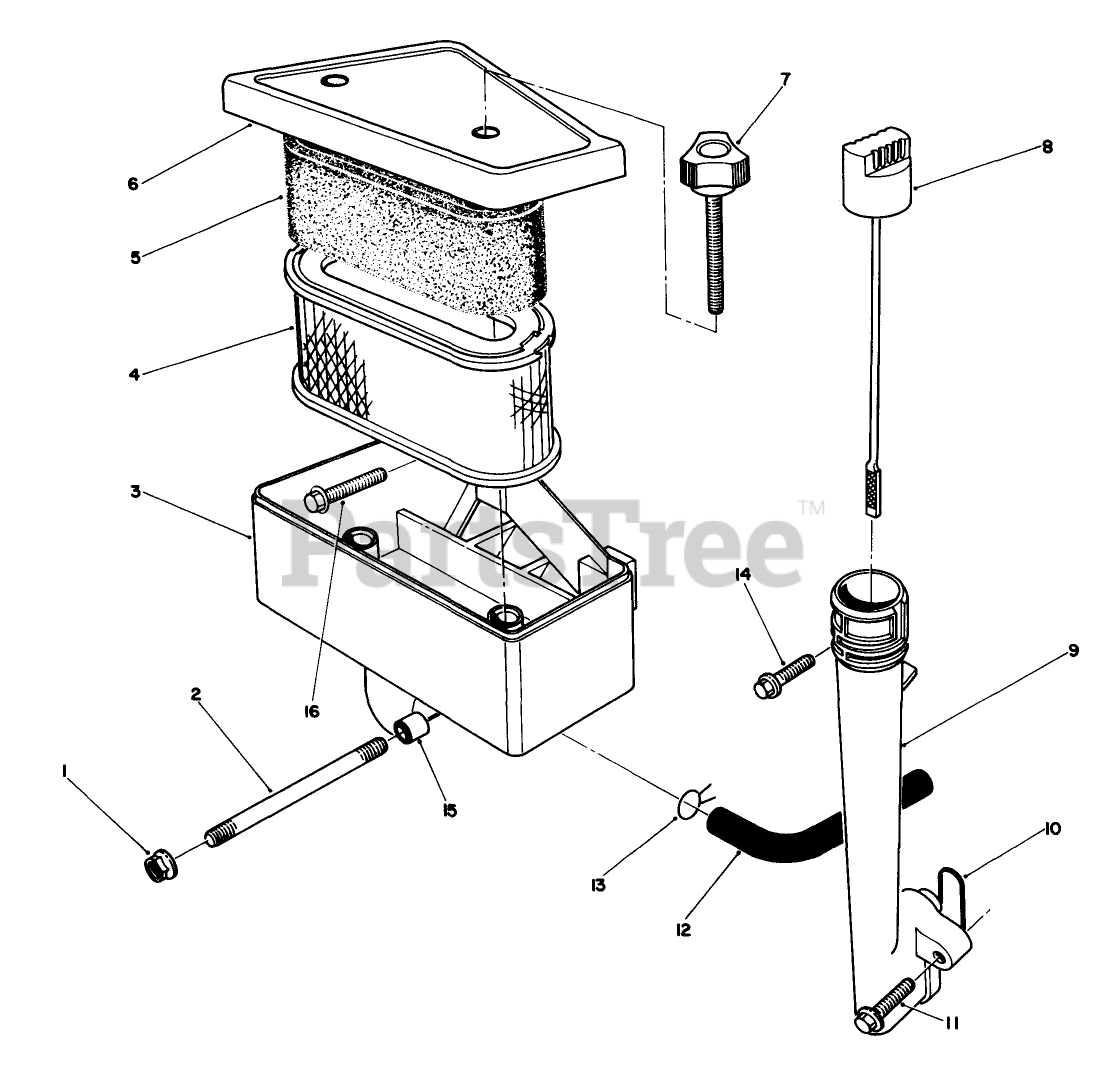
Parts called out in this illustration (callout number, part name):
3	AIR CLEANER BODY
4	AIR FILTER ELEMENT
5	Filter-Foam
6	AIR CLEANER COVER *B
7	RETAINER - COVER
8	Dipstick-Oil
10	O-RING
13	CLAMP F/W ENGINE
15	SPACER
